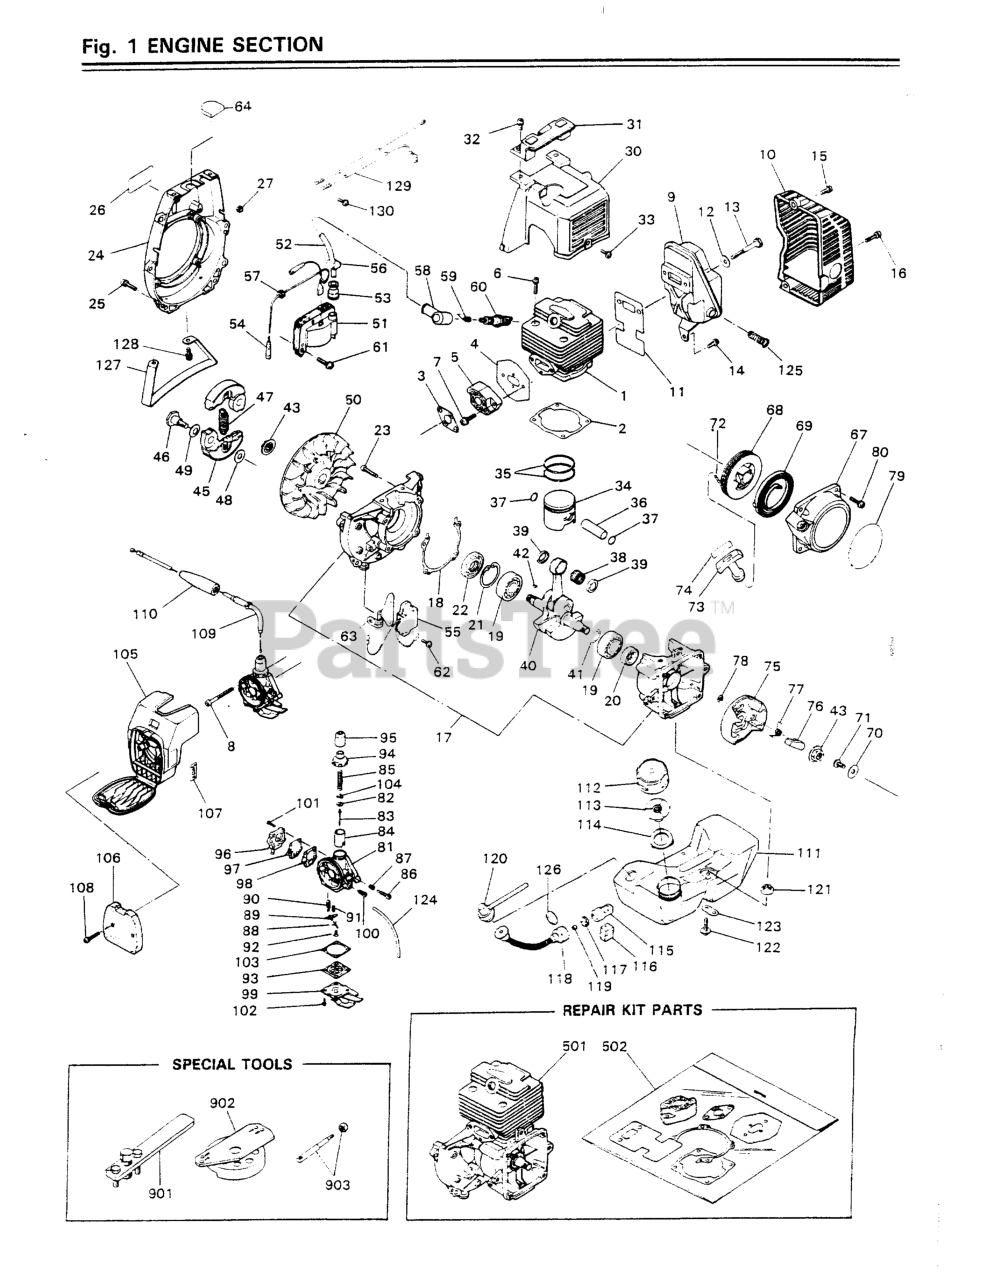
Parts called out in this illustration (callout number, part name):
2	GASKET
5	INSULATOR
7	SCREW (USE 0263-90520 )
8	SCREW, M5 x 45
10	COVER, MUFFLER
12	WASHER, FLAT (USE 182303)
13	BOLT, M6 X 55
15	SCREW (USE 0263-90520 )
16	SCREW, M5 X 30
21	RING, SNAP, M32 x 1.2
22	SEAL, OIL (RPLS 1200-21220)
23	SCREW, M5 x 30(RPLS 0263-00530
25	SCREW, M5 X 20
31	HEAD GUARD
32	SCREW (USE 0263-90520 )
35	RING, PISTON
36	PIN
37	RING, SNAP
38	BEARING
39	WASHER (RPLS 3310-41341)
40	CRANKSHAFT CO
41	SHIM (NO LONGER AVAILABLE)
42	KEY
46	SCREW
47	SPRING, CLUTCH
48	WASHER
49	WASHER (USE -51241)
51	COIL ASSEMBLY
52	CORD
53	CAP
55	UNIT (RPLS -71310)
58	CAP, PLUG
59	SPRING PLUG (RPLS 3310-71320)
61	SCREW (USE 0263-90520 )
62	SCREW, M5 X 14
67	CASE (RPLS -75110)
68	REEL
69	SPRING, SPIRAL
73	KNOB
76	RATCHET
77	SPRING, RETURN
78	E-RING
79	LABEL (USE -75412)
80	SCREW (USE 0263-90520 )
82	RETAINER SPRING
86	SCREW (RPLS -81161)
89	ARM, FLOAT
90	VALVE (USE -81211)
91	SPRING, INLET
92	SCREW, FLOAT
93	DIAPHRAGM
94	CAP, MIXING
95	SEAL, AIR
96	COVER ASSY PU
97	DIAPHRAGM
98	GASKET, PUMP
99	COVER ASSEMBLY
101	SCREW, M3 x 12
102	SCREW, M3 X 8
103	GASKET (NLA)
106	ELEMENT
107	LABEL
108	SCREW, M4 X 22
109	CABLE COMPLETE (NLA)
110	PROTECTOR
113	VALVE, VENT
116	FILTER-A
117	FILTER-B
118	PIPE (NO LONGER AVAILABLE)
121	WASHER
122	SCREW, M5 X 22
124	PIPE (USE 1620-81710)
125	ARRESTER
902	SET BLOCK (TOOL)
903	ROD ASSY (TOOL)
